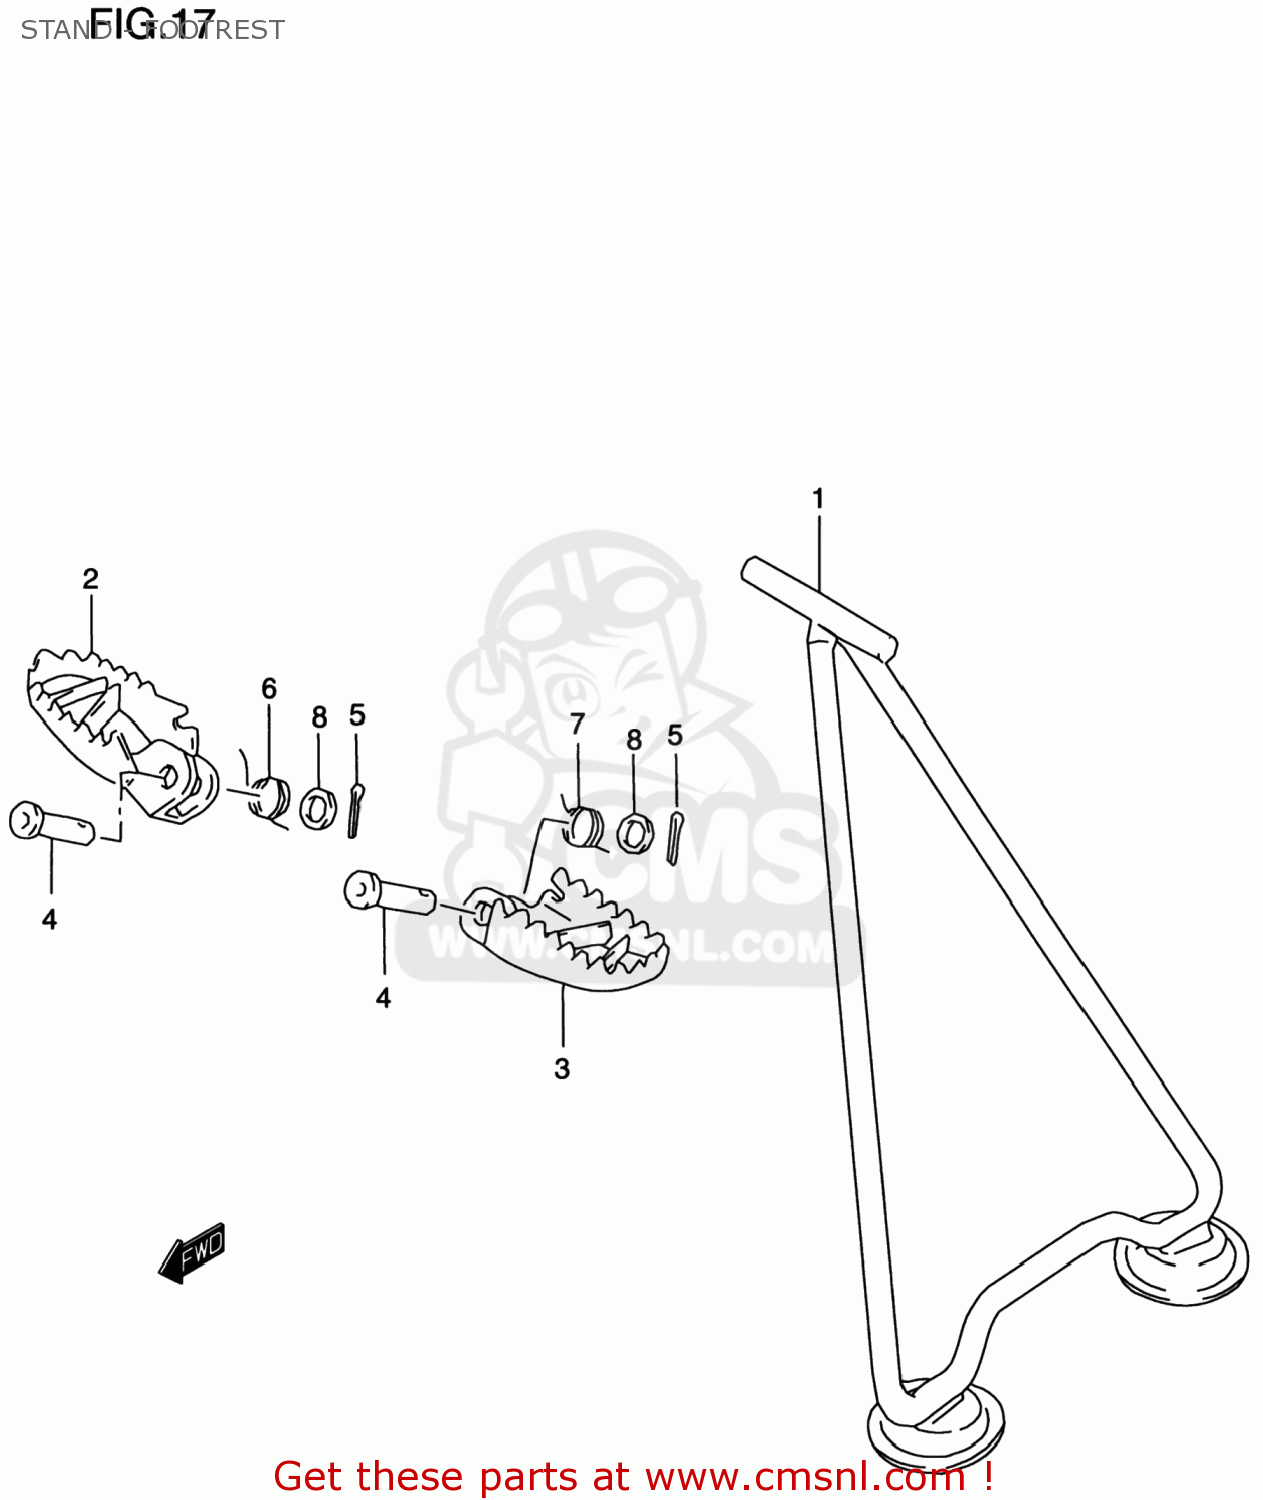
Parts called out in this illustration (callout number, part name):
1	STAND
2	FOOTREST,R
3	FOOTREST,L
4	PIN(10X41.5)
5	PIN 25X20
6	SPRING
7	SPRING
8	WASHER
